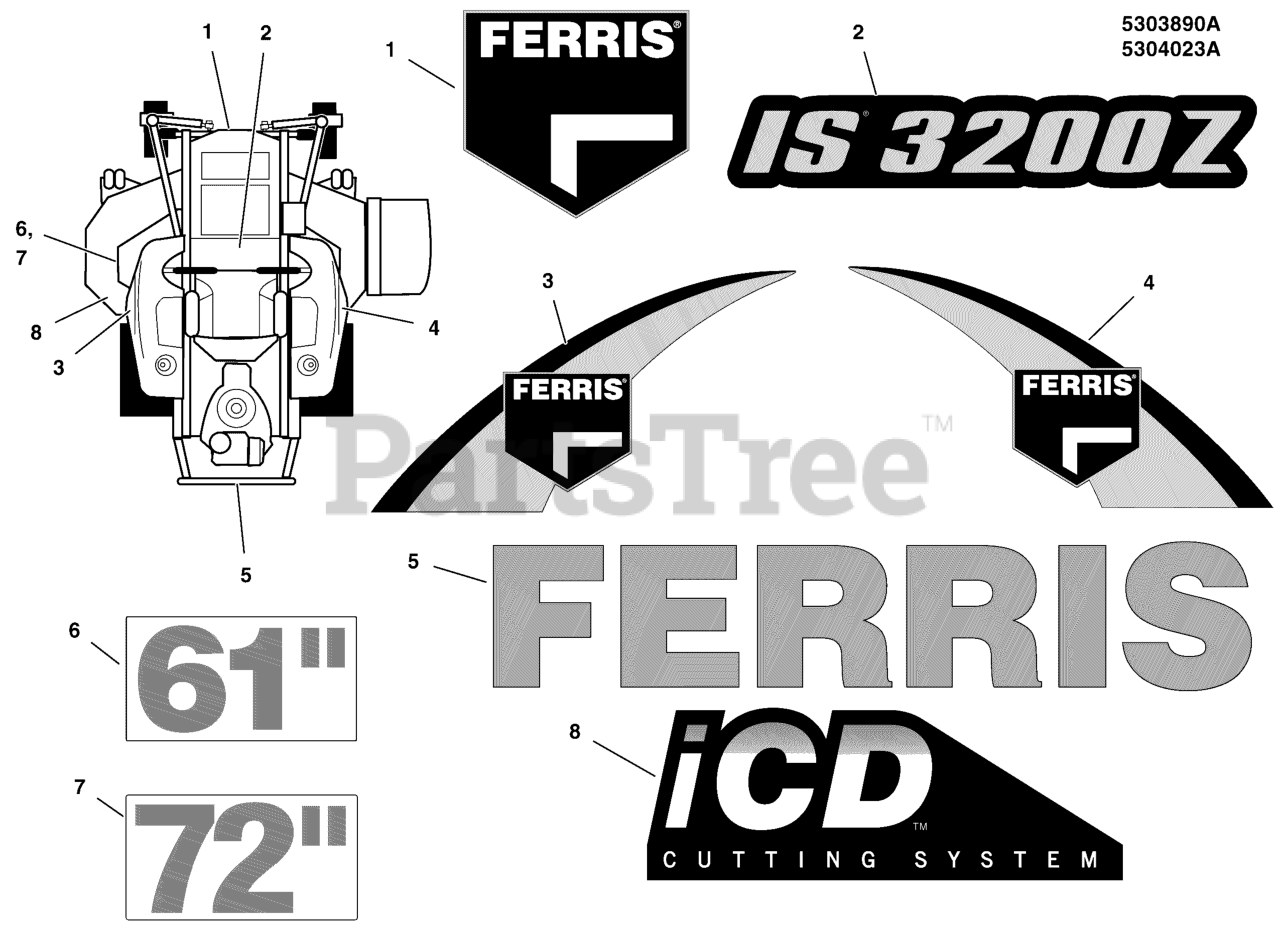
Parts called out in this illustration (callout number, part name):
1	DECAL, BRAND
2	DECAL, MODEL
3	DECAL, Model, Left Hand
4	DECAL, Model, Right Hand
5	DECAL, FERRIS, 2.23" X 11.39"
6	DECAL, 61
7	DECAL, 72
8	DECAL, iCD CUTTING SYSTEM
